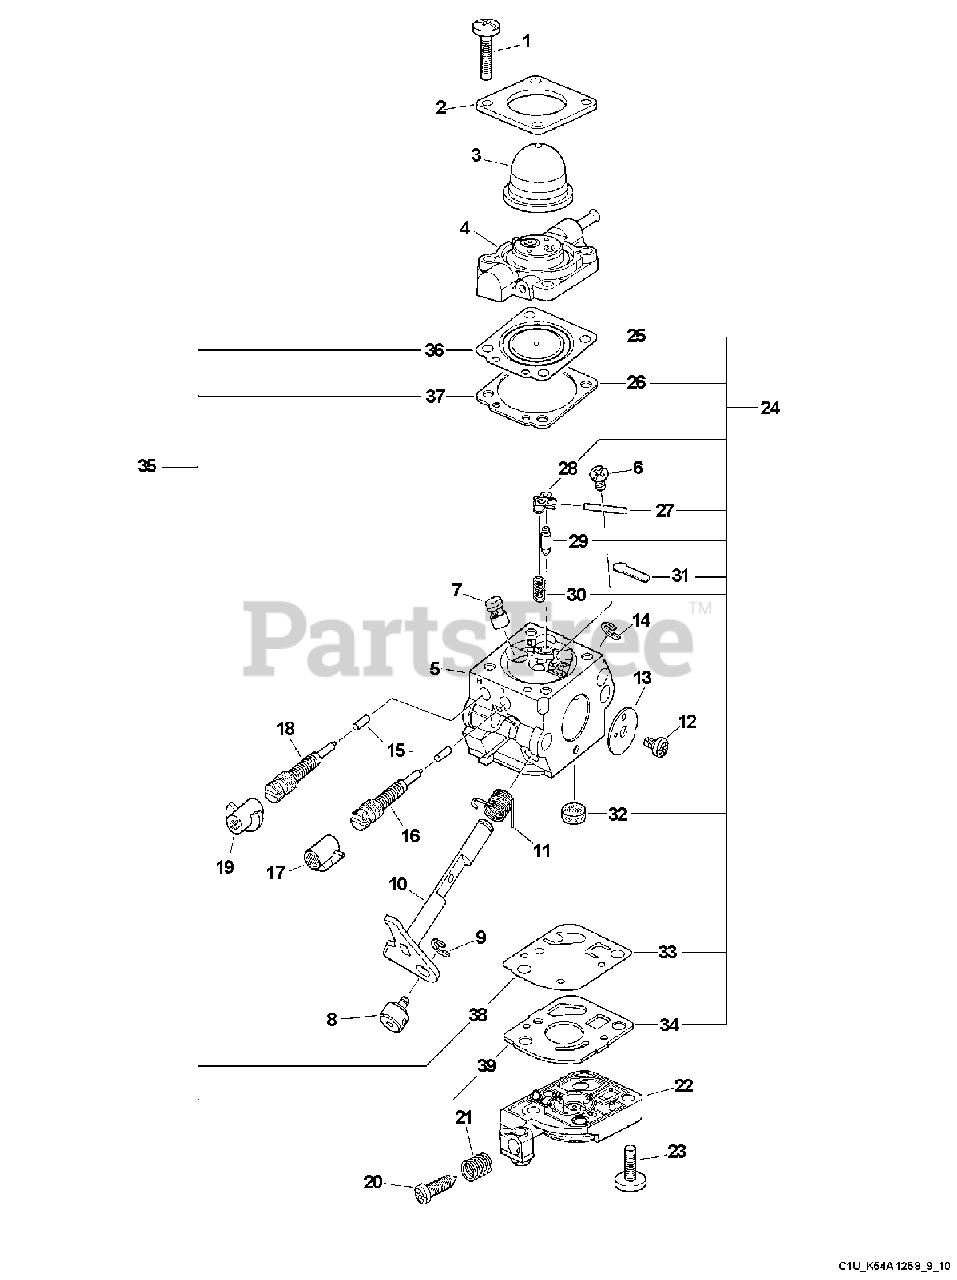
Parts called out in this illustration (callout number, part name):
2	RETAINER, PURGE BULB
3	BULB, PURGE
4	BODY ASSY, PURGE
5	BODY, CARBURETOR
7	NOZZLE, CHECK VALVE
10	SHAFT ASSY, THROTTLE
11	SPRING, THROTTLE RETURN
13	VALVE, THROTTLE
15	RETAINER
16	NEEDLE, MIXTURE
17	CAP, LIMITER - WHITE
18	NEEDLE, HIGH SPEED
19	CAP, LIMITER - RED
20	SCREW, THROTTLE ADJUST
22	COVER, FUEL PUMP
24	REBUILD KIT
25	DIAPHRAGM, METERING
26	GASKET, METERING
27	PIN, METERING LEVER
28	LEVER, METERING
29	VALVE, INLET NEEDLE
30	SPRING, METERING LEVER
31	PLUG, WELCH
32	STRAINER
33	DIAPHRAGM, PUMP
34	GASKET, PUMP
35	GASKET / DIAPHRAGM KIT
36	DIAPHRAGM, METERING
37	GASKET, METERING
38	DIAPHRAGM, PUMP
39	GASKET, PUMP
